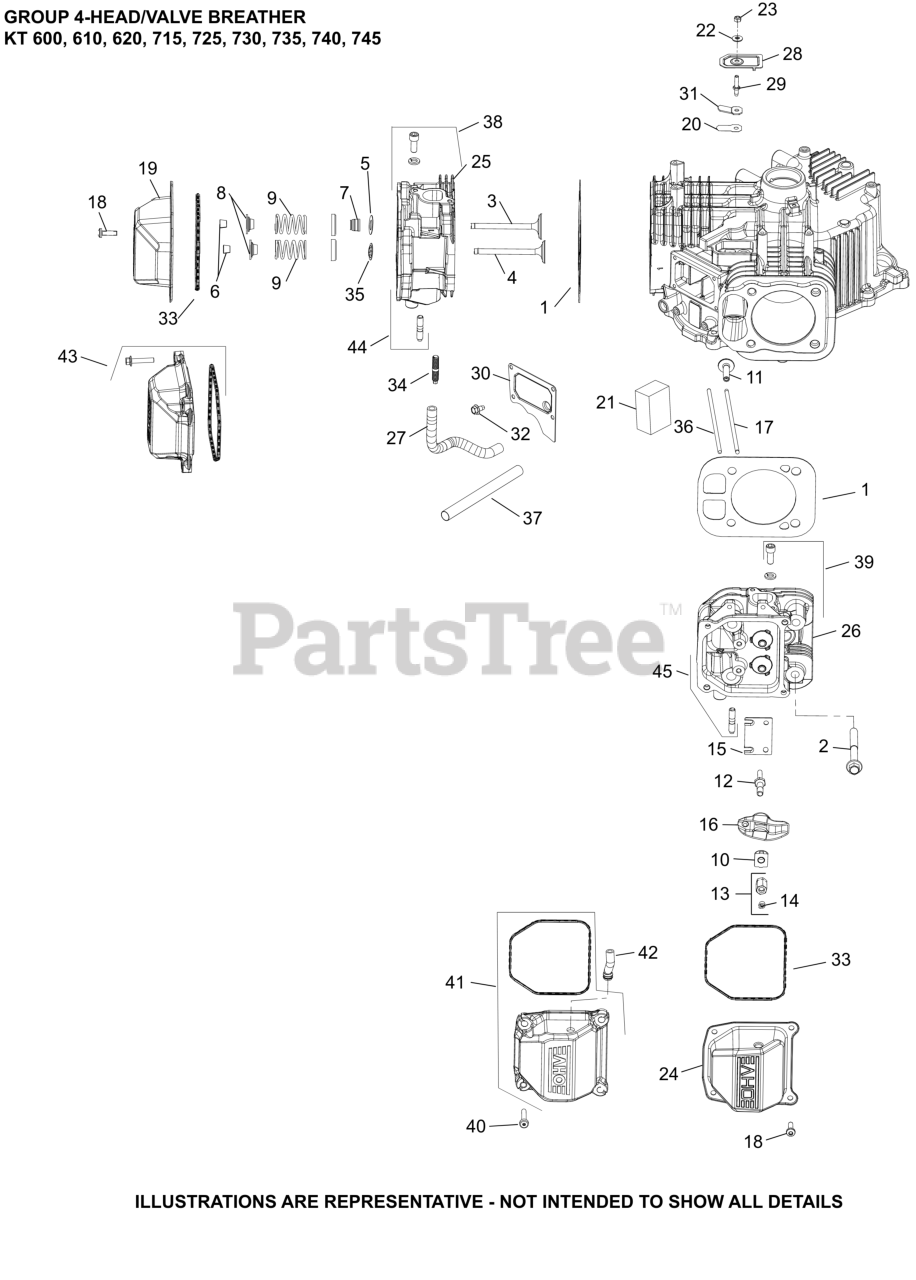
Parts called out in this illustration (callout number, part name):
1	KIT, CYLINDER HEAD GASKET
2	SCREW, FLG M10X1.5X90
3	VALVE, INTAKE
3	VALVE, INTAKE (.25) - (#2401702S)
4	VALVE, EXHAUST
4	VALVE, EXHAUST (.25)
5	SPACER (.010")
6	KIT, RETAINER
7	SEAL, VALVE BAND
8	CAP, VALVE SPRING
9	SPRING VALVE
10	PIVOT, ROCKER ARM
12	STUD, ROCKER
13	HEX NUT ASSEMBLY
14	SCREW, SET
15	PLATE, GUIDE
16	ARM, ROCKER
17	ROD, PUSH
20	REED, BREATHER
21	FILTER, BREATHER
22	WASHER, SEALING
23	NUT, LOCK M5X.8
27	HOSE, BREATHER
28	COVER, BREATHER REED
30	COVER, BREATHER MEDIA
31	RETAINER, REED
33	O-RING (YELLOW), VALVE CO
35	RETAINER, VALVE GUIDE (KM)
41	KIT,BREATHER VALVE COVER (PLASTIC)
42	HOSE, FP-USE 32 326 07-S(PLASTIC COVERS)
43	KIT, VALVE COVER-PLAIN (PLASTIC)
44	HEAD, ASSEMBLY CYLINDER (#1)
45	HEAD, ASSEMBLY CYLINDER (#2)
NI	SCREW, FLG M6X1.0X30
